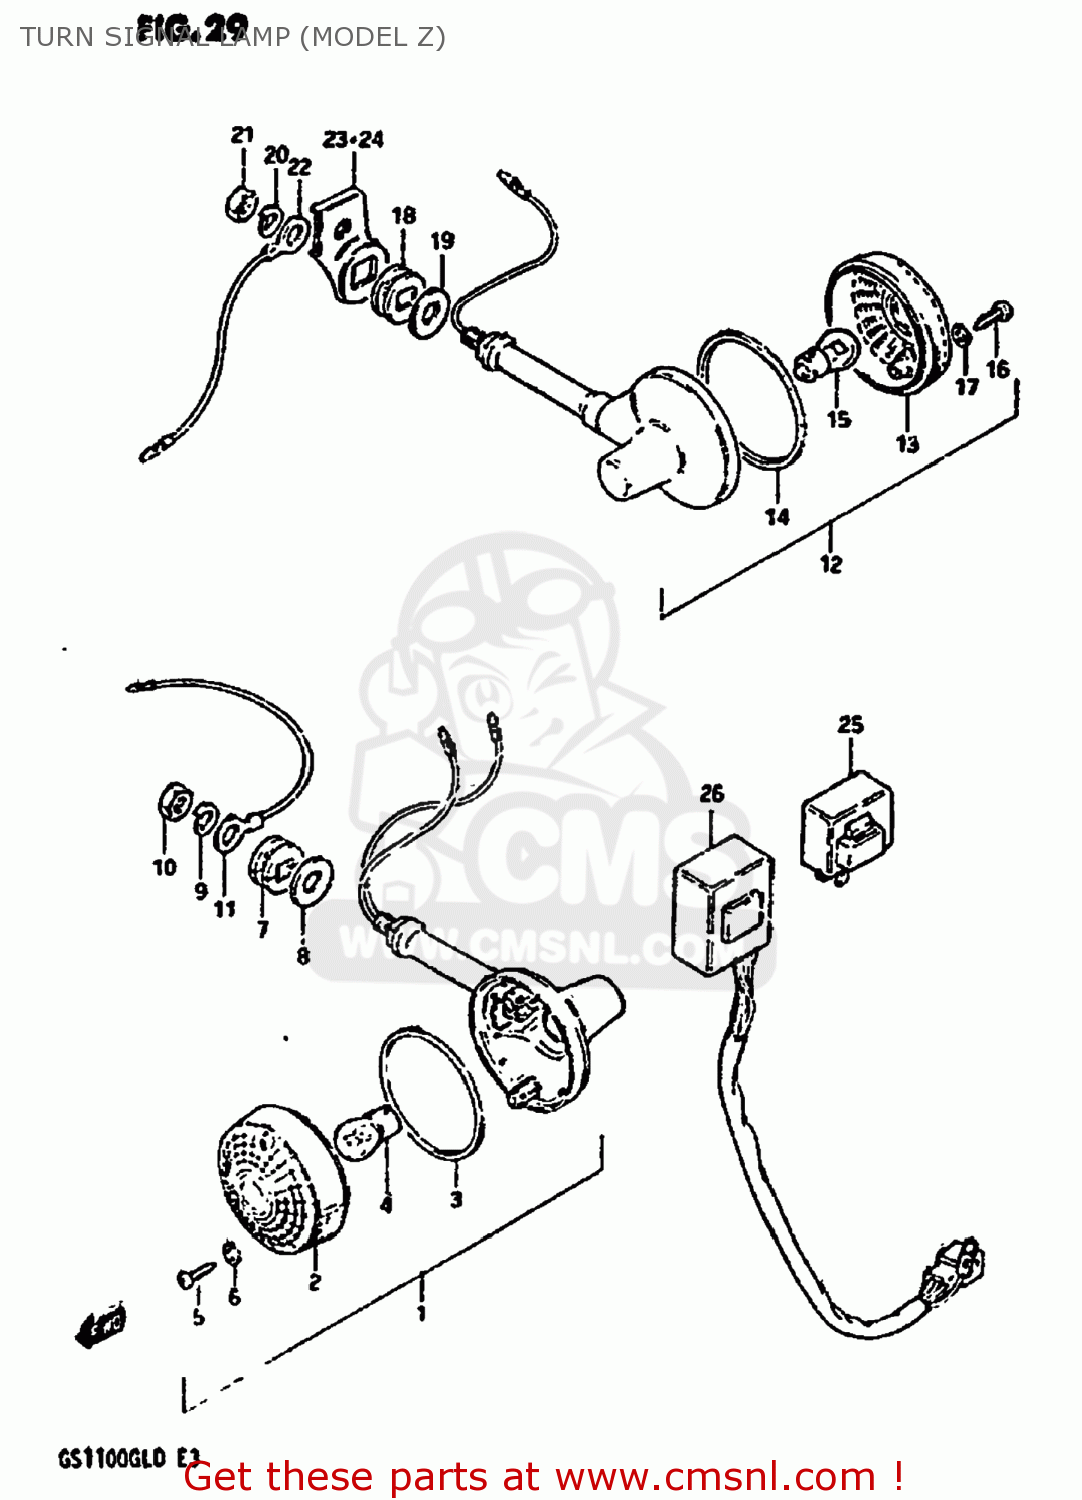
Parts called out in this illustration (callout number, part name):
1	LAMP ASSEMBLY,FRONT TURN SIGNAL
2	LENS
3	GASKET (NAS)
4	BULB(12V23W)
5	SCREW
6	GASKET (NAS)
7	CUSHION
8	WASHER (10.5X30X2.3)
9	LOCK WASHER
10	NUT
11	LEAD WIRE,EARTH
12	LAMP ASSEMBLY,REAR TURN SIGNAL
13	LENS
14	GASKET (NAS)
15	BULB(12V23W,STANLEY,A4577A)
16	SCREW
17	GASKET (NAS)
18	CUSHION
19	WASHER (10.5X30X2.3)
20	LOCK WASHER
21	NUT
22	LEAD WIRE,EARTH
23	BRACKET,REAR TURN SIGNAL
24	BRACKET,REAR TURN SIGNAL
25	RELAY ASSY,TURNSIGNAL
26	UNIT,TURN SIGNAL CONTROL
